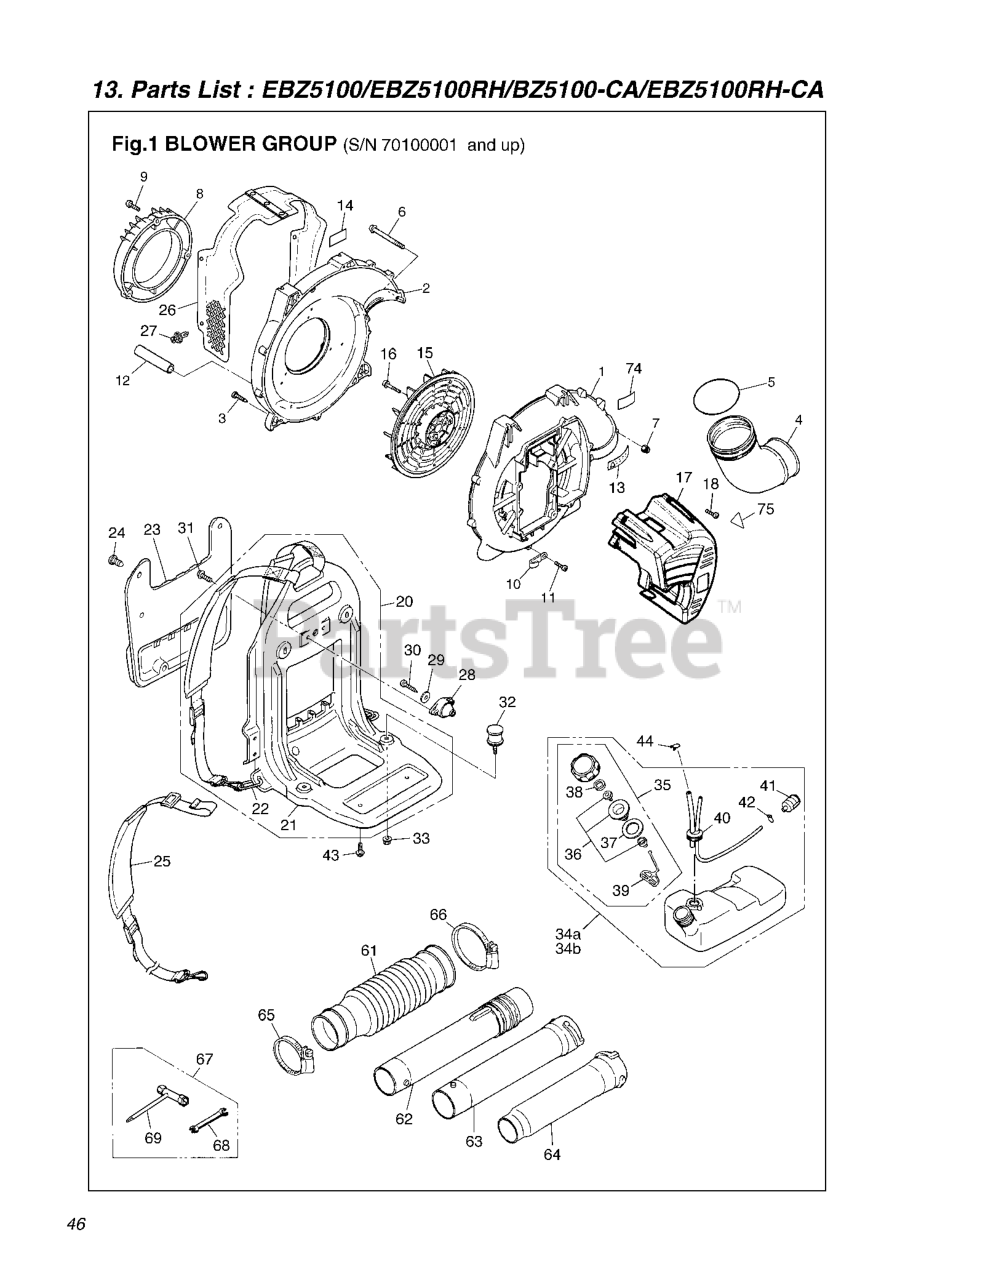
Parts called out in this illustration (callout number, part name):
1	VOLUTE CASE
2	VOLUTE COVER
3	SCREW
4	PIPE BEND
6	BOLT,TORX, M5X70
7	RP_NUT (B)
9	SCREW
10	CLAMP (BT Only)
12	RP_TUBE (RPLS 0727001507)
13	LABEL, CAUTION(RPLS 275031910)
14	LABEL, NET
17	ENGINE COVER
18	SCREW
21	FRAME COMP.
22	RING (RPLS 349021120)
24	CLIP (RPLS 3490-21320)
25	BAND ASSY. (BUCKLE 275632910)
26	NET COMP (RPLS-T402325430)
27	CLIP
28	DAMPER
29	WASHER
30	SCREW (RPLS T497054010)
32	DAMPER
33	NUT (M6)
34A	TANK ASSY.
35	CAP ASSY
36	HOLDER (RPLS 450085230)
37	PACKING
38	FILTER
39	STOPPER
40	PIPE COMPLETE
41	FILTER ASSY EXT WHITECAP
42	CLIP
44	CLIP
61	BELLOWS
62	SWIVEL JOINT (RP 275051200)
63	PIPE, STRAIGHT(RPLS 681151210)
64	PIPE, END RPLS 848L0L65E0
65	CLAMP***
66	CLAMP***
67	TOOL-SET
68	SPANNER,8x10(RPLS 090100810
69	SOCKET
75	RP_LABEL, HOTMARK
